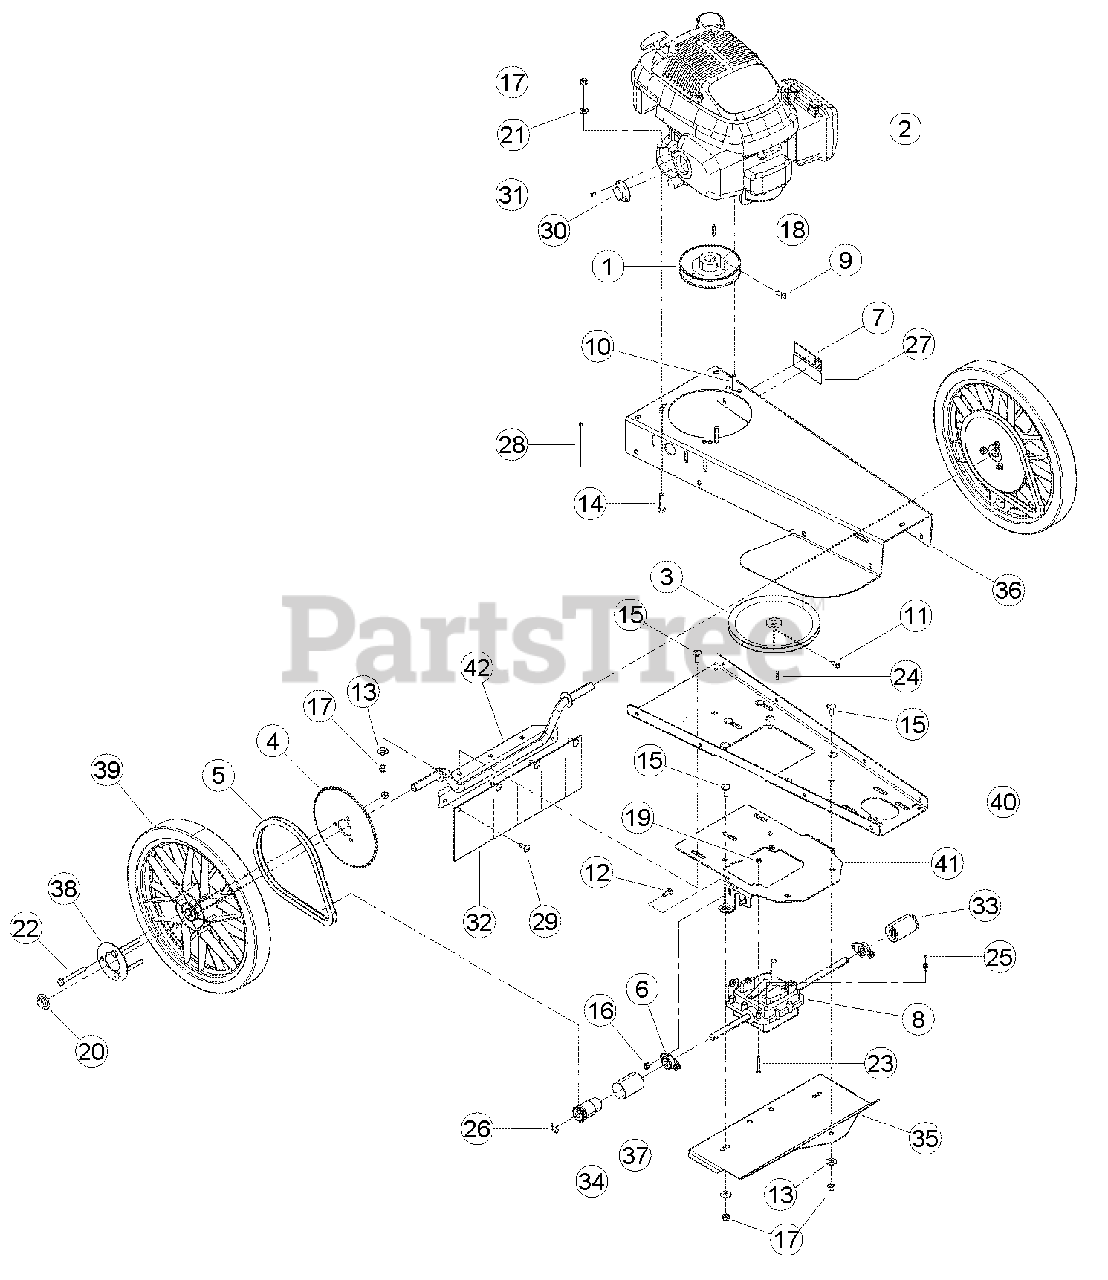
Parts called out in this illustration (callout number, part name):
1	PULLEY, 5.0 X 7/8 AB
2	ENGINE, 6.5 HP QUANTUM HD 49 STATE (CALIF. EMISSION COMPLIANT) (FOR SERVICE SEE ENGINE OWNER'S MANUAL OR YOUR NEAREST AUTHORIZED HONDA ENGINE DEALER.)
3	PULLEY, 7-1/2 X 12MM A GROOVE
4	SPROCKET, 35A60 W/HOLES
5	CHAIN, EZ TRIMMOWER
6	BEARING, 1/2 FLANGE
7	DECAL, 6.5 HP SP INFORMATION
8	TRANSMISSION, 3 SPEED
9	SCREW, 5/16-18 X 5/8 SQ HD SET
10	BOLT, 5/16 X 2-1/2 HEX HD GR5 ZP
11	SET SCREW, 1/4 X 5/8 SQ HD
12	BOLT, 1/4 X 3/4 CRG GR5 ZP
13	WASHER, 5/16 FLAT ZP
14	BOLT, 5/16 X 1-1/2 HEX HD GR5 ZP
15	BOLT, 5/16 X 7/8 CRG GR5 NC ZP
16	NUT, 1/4 NE NYLOCK ZP
17	NUT, 5/16 NE NYLOCK ZP
18	KEY, 3/16 SQUARE X 1.00 LONG
19	NUT, 10/24 NYLOCK TYPE NM, ZP
20	PUSHNUT, 5/8 ZP
21	WASHER, 5/16 SAE FLAT ZP
22	BOLT, 5/16 X 2-3/4 HCPS GR5
23	SCREW, #10X24 X 1-1/2 PAN PHP ZP
24	KEY, 4MM SQUARE X 20 MM
25	SCREW, #8-32 X 3/16 KNR CUP PT
26	CLIP, 1/2" E
27	DECAL, SERIAL NUMBER
28	STRAP, 4 IN. BLACK
29	RIVET, PLASTIC 1/4 X 7/8
30	MUFFLER DEFLECTOR, HONDA 5.5 HP GCV
31	SCREW, MUFFLER DEFLECTOR
32	FLAP, TRIMMER
33	WELDMENT, LH WHEEL CLUTCH
34	WELDMENT, RH WHEEL CLUTCH
35	PAN, TRIMMER BOTTOM
36	BODY, TRIMMER
37	TUBE, 1.5" X 2.125" HEAT SHRINK
38	SHEET, CAP WHEEL
39	ASSEMBLY, TRIMMER WHEEL
40	BOTTOM, TRIMMER FRAME
41	PLATE, TRANSMISSION
42	WELDMENT, TRIMMER AXLE
